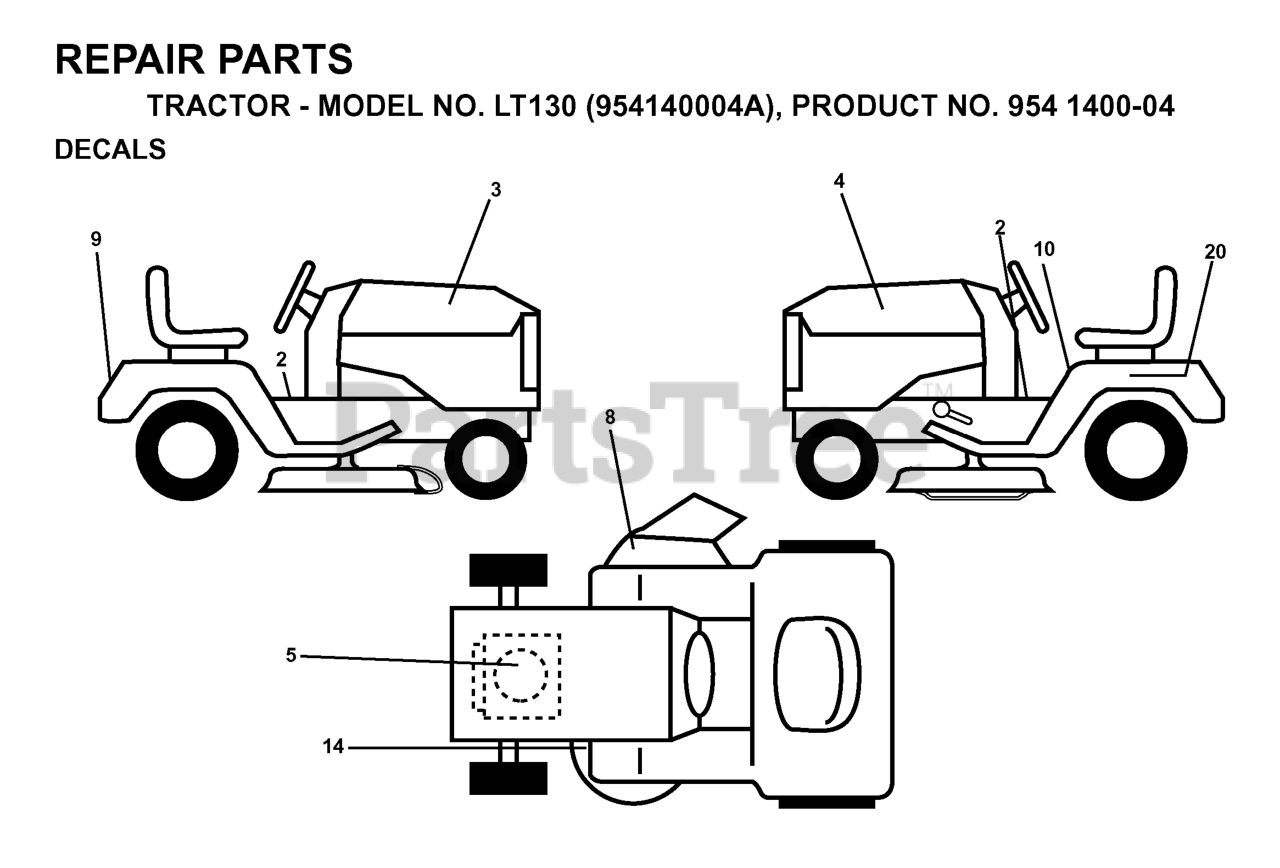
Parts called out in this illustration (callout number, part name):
2	DECAL FEND STLT OPER INST E/F
3	DECAL HOOD LH LT130
4	DECAL HOOD RH LT130
5	DECAL HP ENGINE
8	DECAL WARNING (ENGLISH/FRENCH)
9	DECAL FENDER HUSQ
10	DECAL FENDER DANGER
14	DECAL V-BELT SCHEMATIC
20	DECAL, BATTERY DANGER
